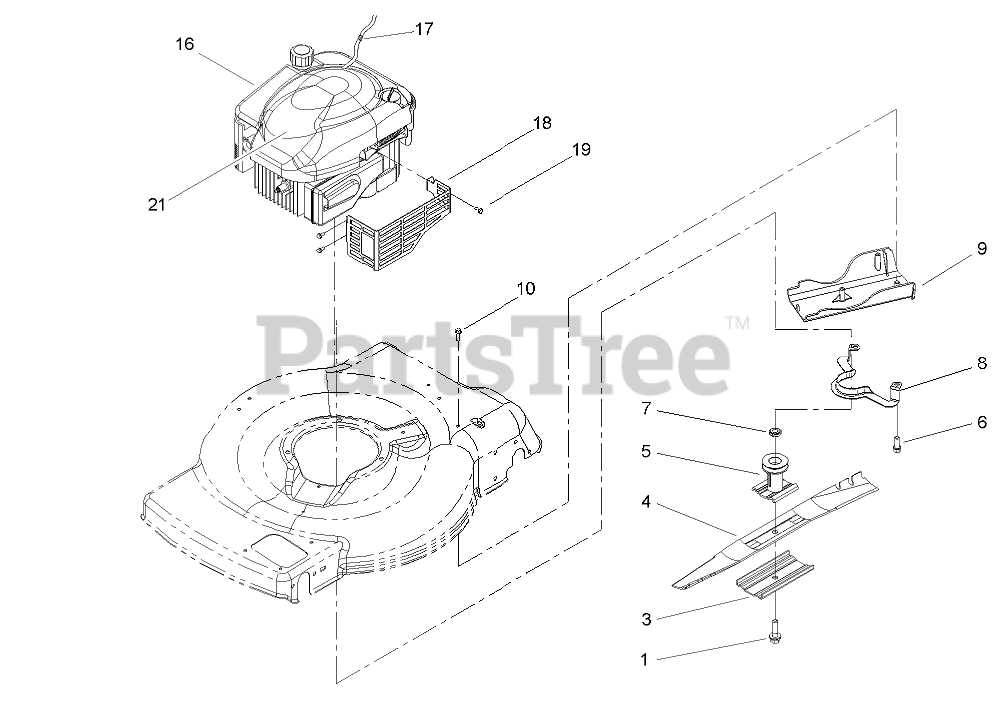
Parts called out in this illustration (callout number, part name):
1	BOLT-BLADE
3	Accelerator-Blade
4	BLADE-22 INCH
5	DRIVER-BLADE
6	SCREW-TAPTITE
7	Spacer-Driver
8	Guide-Belt
9	Cover-Belt, Rear
10	SCREW-HWH
17	STOP-ROPE
18	SHIELD-MUFFLER
19	SCREW-TAPTITE
21	DECAL-RECOIL
